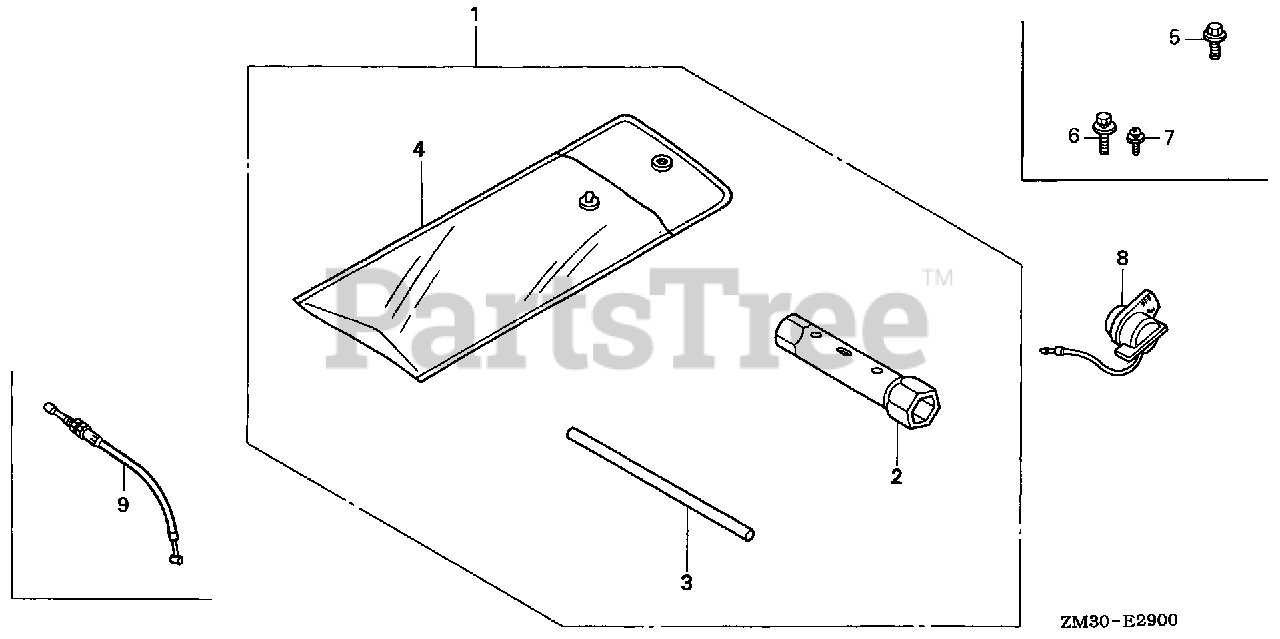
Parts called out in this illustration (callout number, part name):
1	TOOL KIT
2	WRENCH, SPARK PLUG
3	BAR A, HANDLE
4	BAG, TOOL (160MM)
